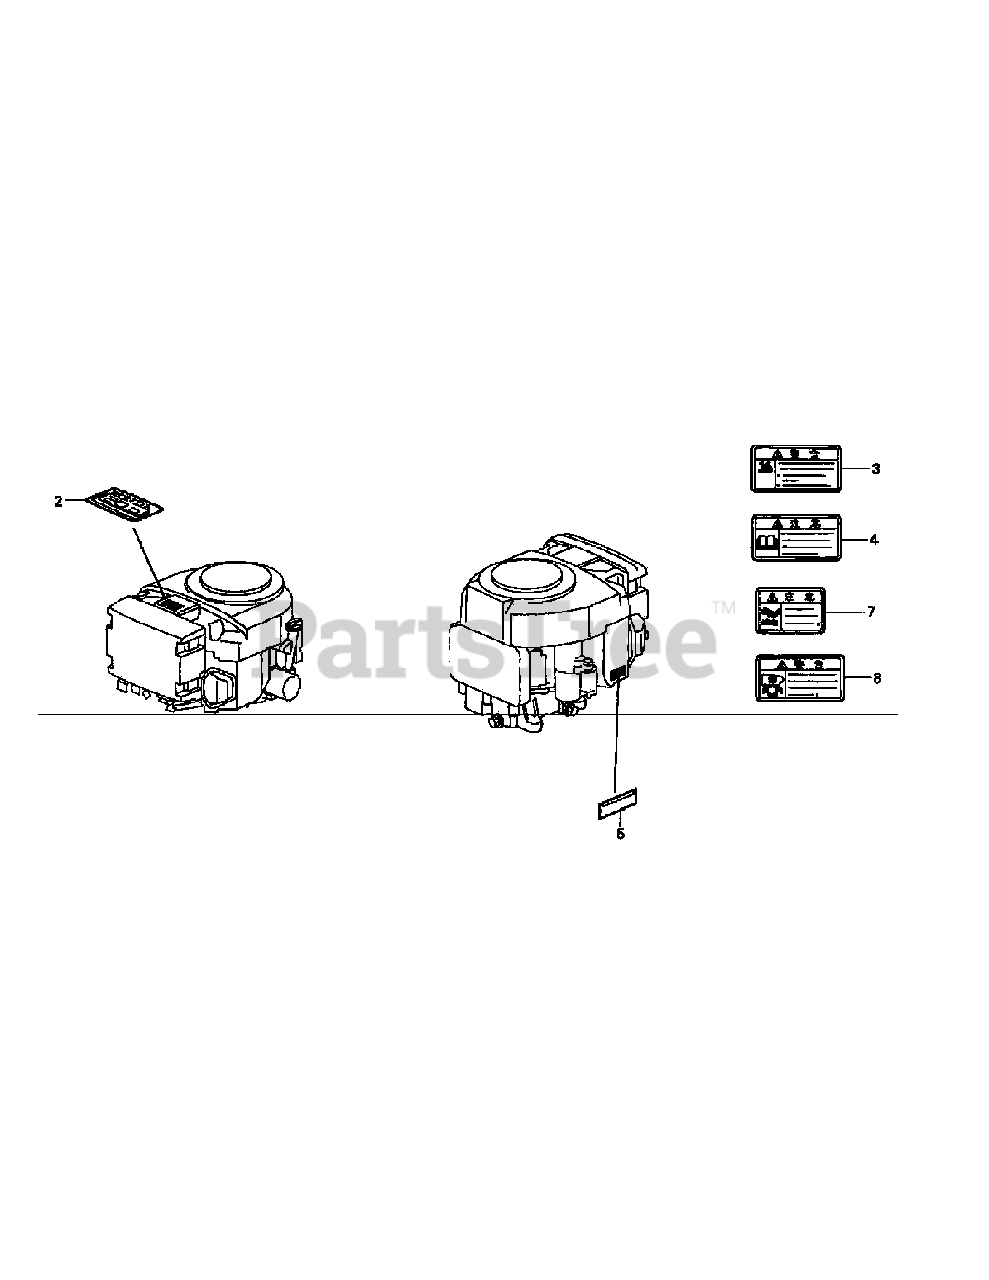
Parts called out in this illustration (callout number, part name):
2	Emblem Mark
3	Fuel Warning Mark
4	Caution Mark
5	Specification Label (GXV620)
7	Heat Caution Mark
8	Exhaust Gas Warning Mark
